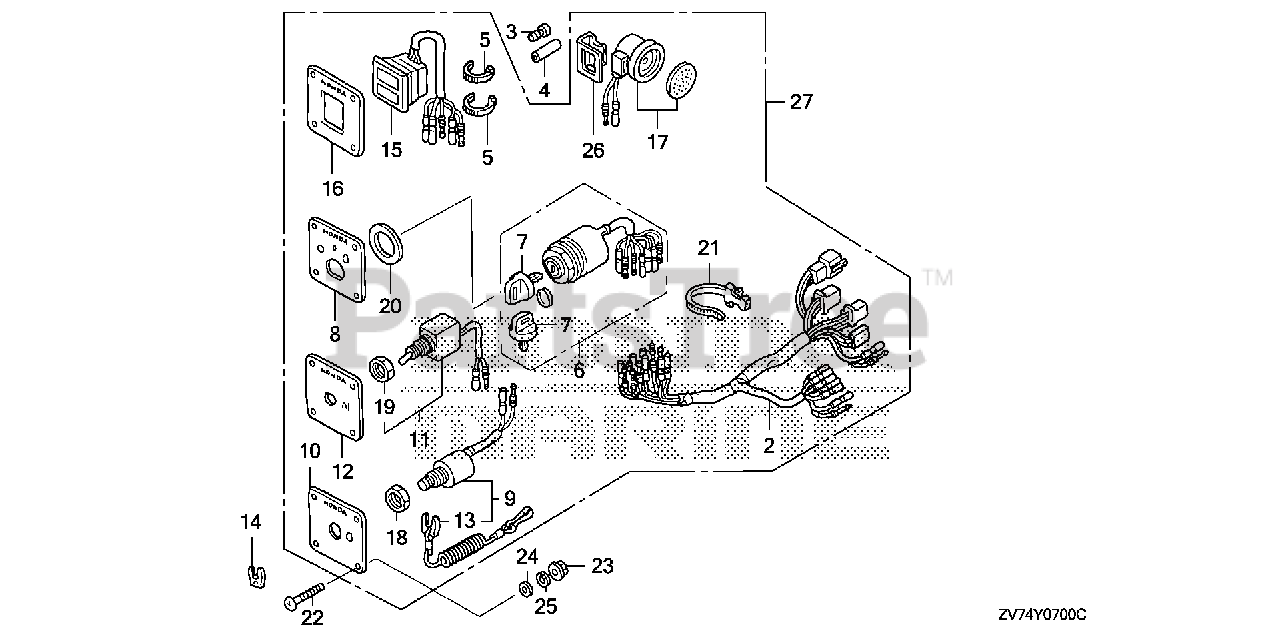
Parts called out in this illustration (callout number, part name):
1	PANEL KIT, CONTROL (B)
2	HARNESS ASSY., SWITCH PANEL
3	PLUG, CONNECTOR (INNER)
4	PLUG, CONNECTOR (OUTER)
5	TIE, CABLE (2.4X92) (NATURAL)
6	SWITCH ASSY., COMBINATION
7	KEY ASSY., COMBINATION SWITCH (35100-ZV5-003 ONLY)
8	PANEL, SWITCH
9	SWITCH ASSY., EMERGENCY STOP
10	PANEL, EMERGENCY STOP SWITCH
11	SWITCH ASSY., SOLENOID
12	PANEL, SOLENOID
13	WIRE, EMERGENCY
14	CLIP, EMERGENCY LOCK
15	LAMP ASSY., INDICATOR (2-LED)
16	PANEL, INDICATOR
17	BUZZER, WARNING
18	NUT, HEX. (16MM)
19	NUT, HEX. (12MM)
20	WASHER, PLAIN
21	BAND, WIRE HARNESS (150MM) (NATURAL)
22	SCREW, PAN (5X40)
23	NUT, FLANGE (5MM)
24	WASHER, PLAIN (5MM)
25	WASHER, SPRING (5MM)
26	BRACKET, BUZZER
27	PANEL ASSY., CONTROL (TYPEB)
